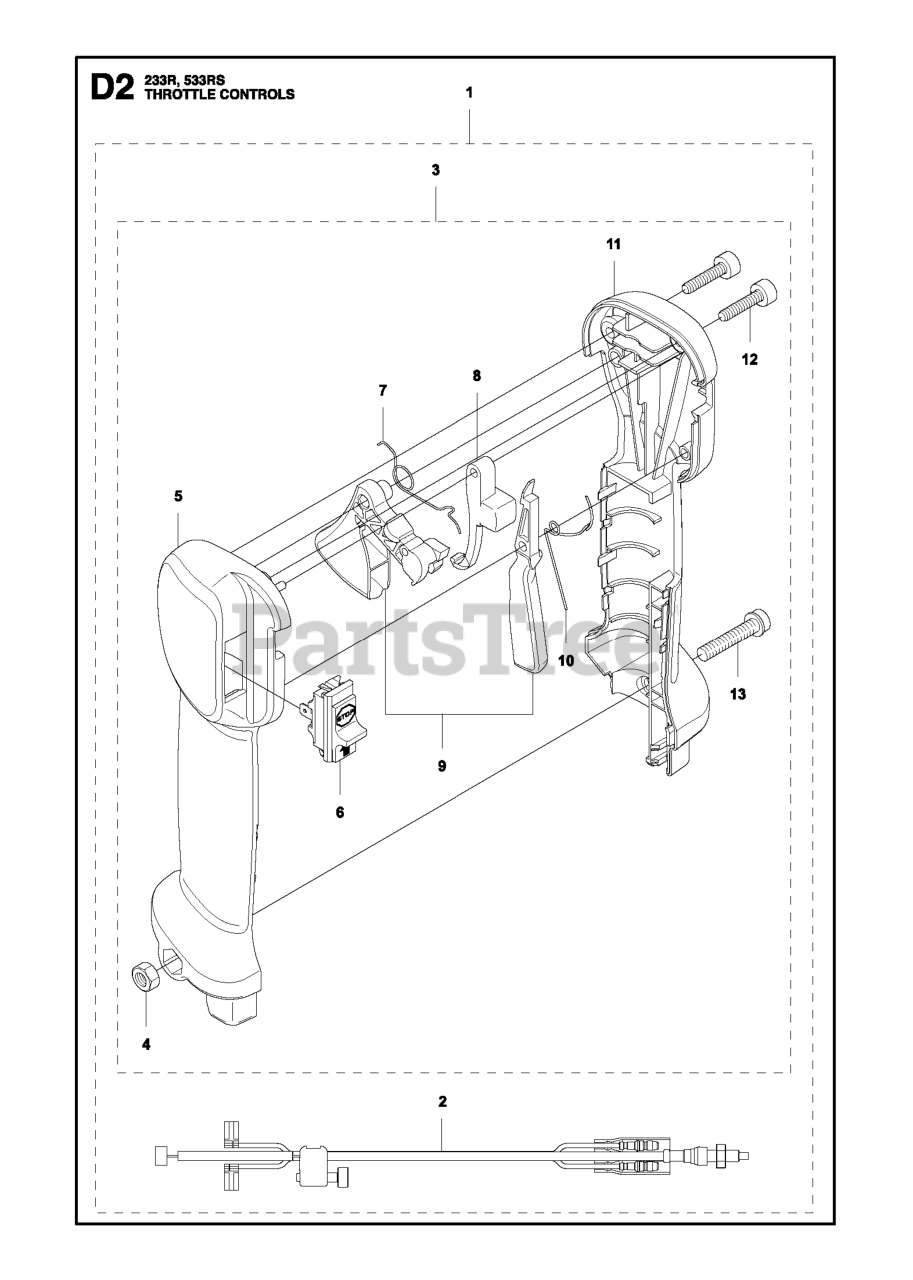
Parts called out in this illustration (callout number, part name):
3	HANDLE SYSTEM ASSY
6	START/STOP SWITCH
8	STARTER THROTTLE LOCK
9	THROTTLE CONTROL
12	SCREW IHSCT MT4X18 10.9 ZN/FE
13	SCREW IHSCFM
